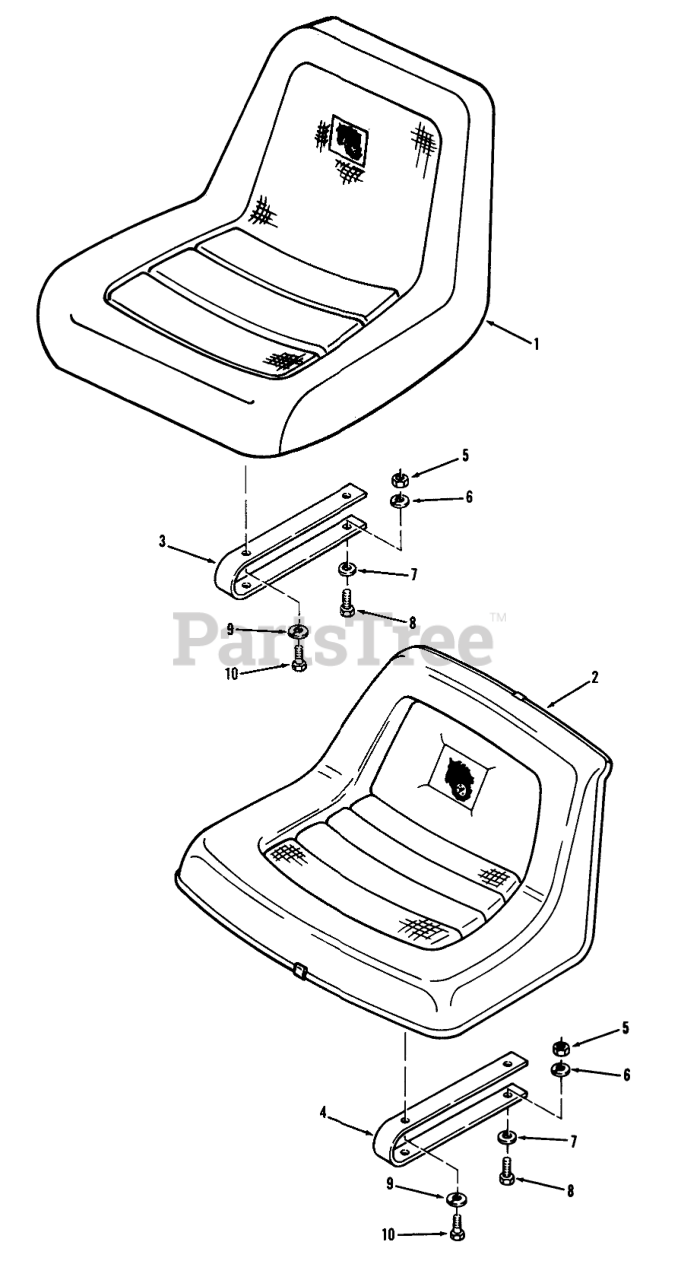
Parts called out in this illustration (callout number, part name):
1	Seat
2	Seat
3	Seat Spring
4	Spring
5	Nut
6	Lockwasher
7	WASHER 5/16 SAE
8	HHCS
9	Lockwasher
10	Bolt
